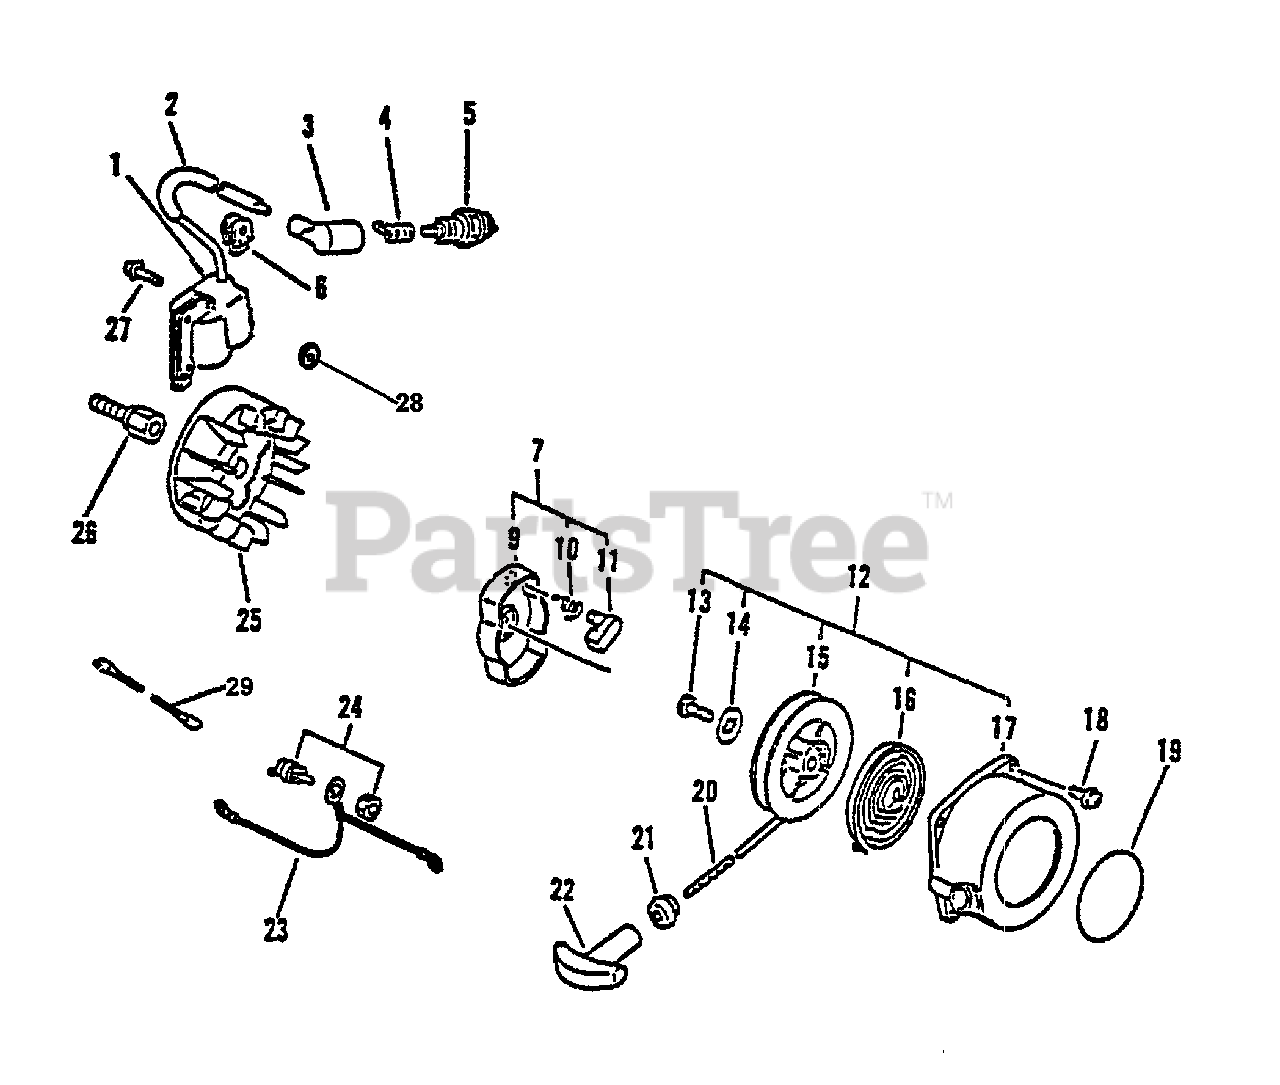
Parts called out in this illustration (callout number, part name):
1	COIL, IGNITION
3	CAP, SPARK PLUG
4	TERMINAL, SPARK PLUG
5	SPARK PLUG - BPM7A
5	SPARK PLUG - BPMR7A
7	PAWL ASSY, STARTER
9	CATCHER, PAWL
10	SPRING, RETURN
11	PAWL, STARTER - BLACK
12	STARTER ASSY
13	SCREW
14	WASHER
15	REEL, ROPE
16	SPRING, RECOIL
17	CASE, RECOIL STARTER
18	SCREW 4×18
19	LABEL, ECHO
21	GUIDE, ROPE
22	GRIP, STARTER
23	LEAD - GROUND
24	SWITCH, ON-OFF
25	FLYWHEEL
26	HUB, FAN
27	SCREW 4×22
28	COLLAR
29	LEAD
